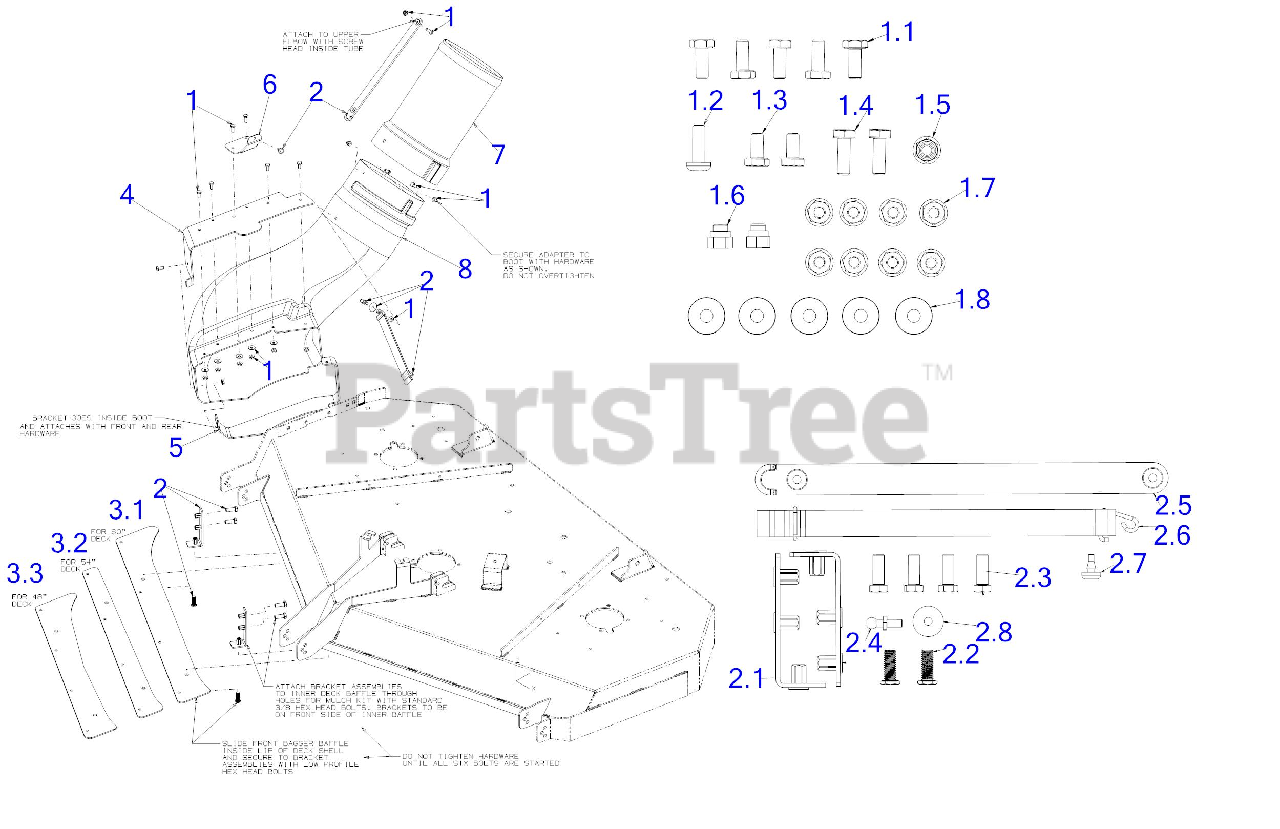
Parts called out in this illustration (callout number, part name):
1	HARDWARE PACK
1.1	SCREW 1/4-20 x .620 GR5
1.2	SCREW 1/4-20X.75
1.3	SCREW 1/4-20X.5 GR5
1.4	SCREW 1/4-20X.75 GR5
1.5	FLANGE LOCK NUT
1.6	HEX ACORN NUT
1.7	LOCK NUT 1/4
1.8	SPRING WASHER BELL
2	HARDWARE PACK
2.1	BRACKET ASSEMBLY-BAFFLE MTG 48/54/60 FAB
2.2	SCREW 3/8-16X1.0 GR5 SPEC
2.3	SCREW 3/8-16 x 1 GR5
2.4	PIN 1/4-20
2.5	CHUTE STRAP
2.6	CHUTE STRAP
2.7	RUBBER BUMPER
2.8	FLAT WASHER
7	BAGGER CHUTE ADAPTER
8	BAGGER LOWER CHUTE
